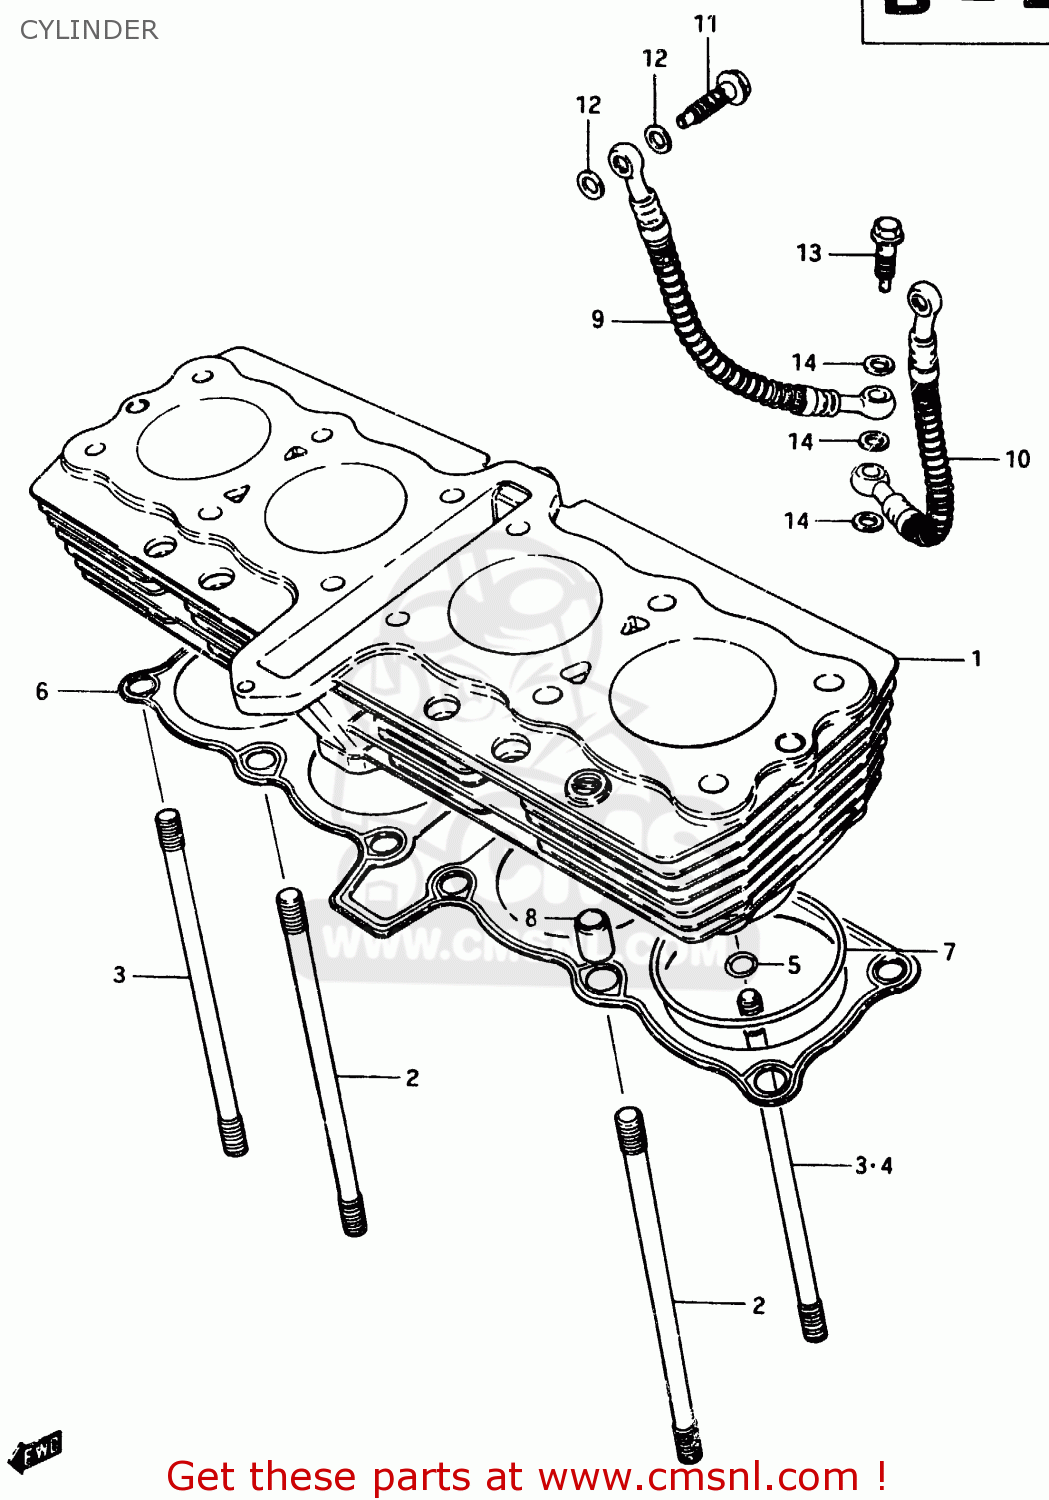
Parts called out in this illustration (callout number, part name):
1	CYLINDER
2	STUD
3	STUD
4	STUD
5	O RING(D:2.4,ID:11)
6	GASKET,CYLINDER
7	O RING(D:2,ID:70)
8	PIN
9	HOSE,OIL
10	HOSE,OIL
11	BOLT UNION
12	GASKET 8.2X14X1 (NAS)
13	BOLT,OIL PIPE
14	WASHER(10X15X1.5)
